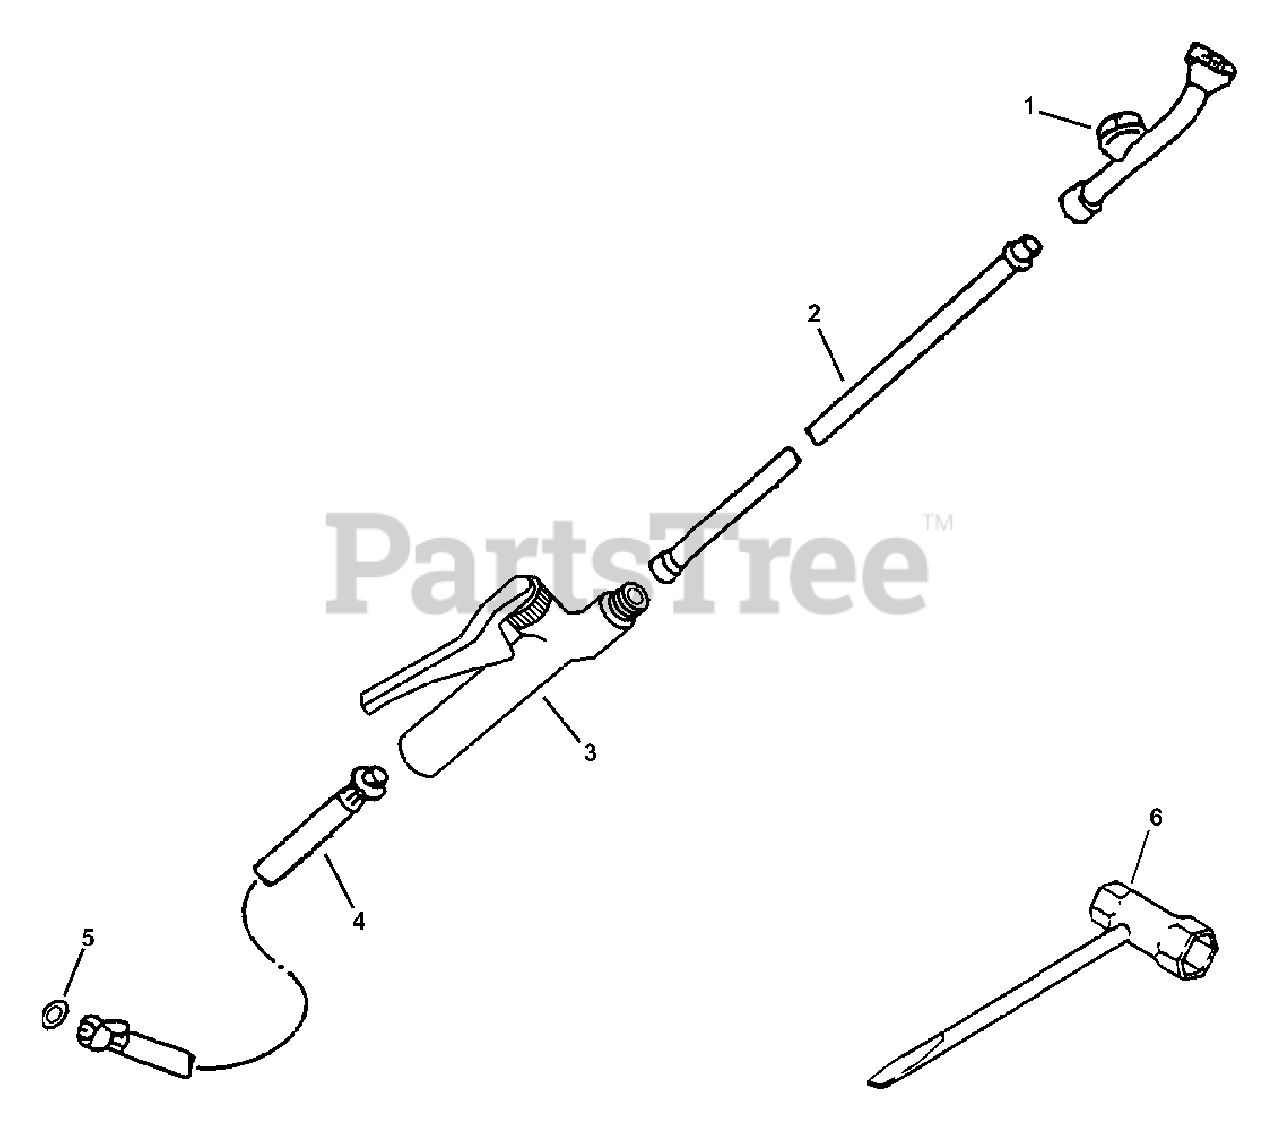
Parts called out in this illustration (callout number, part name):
1	NOZZLE, 2-HEAD
2	TUBE, NOZZLE
3	GRIP, WAND
4	HOSE, SPRAY
5	GASKET, BYPASS NOZZLE
6	T-WRENCH 10×19 MM
